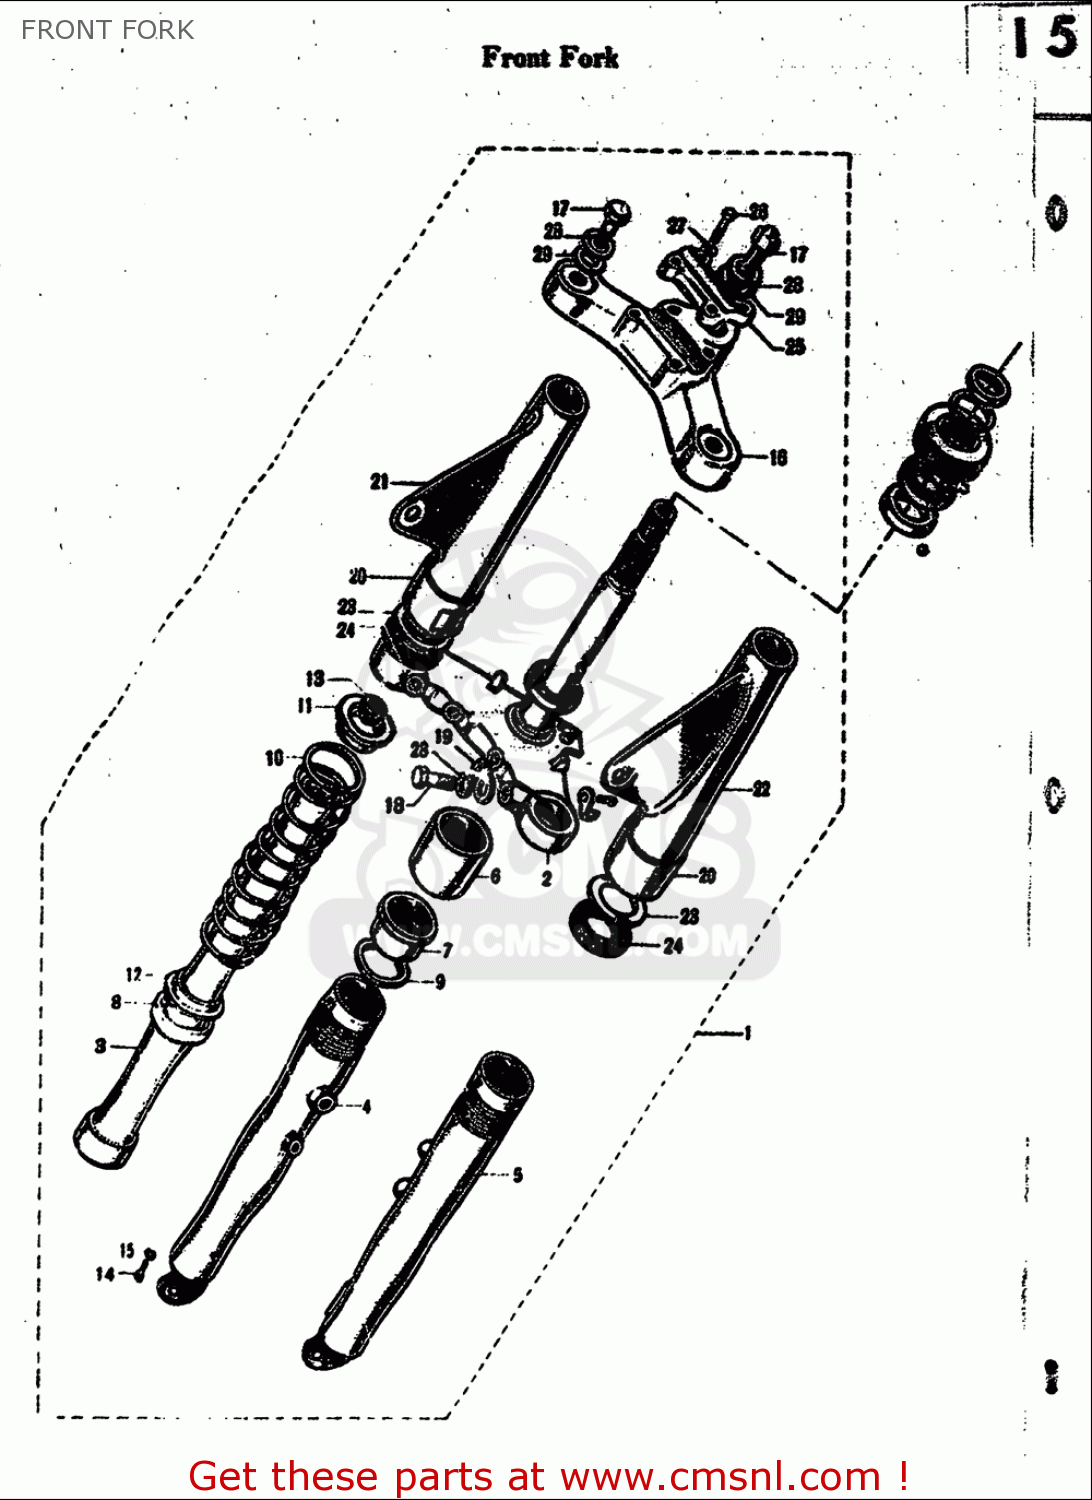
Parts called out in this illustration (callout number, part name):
7	GUIDE,FORK INNER TUBE
12	GUIDE,FRONT FORK SPRING
14	OIL DRAIN PLUG
15	GASKET,DRAIN,PLUG (NAS)
18	BOLT
19	CLIP,SPEEDOMETER CABLE
26	BOLT
27	WASHER,LOCK
28	WASHER,LOCK
